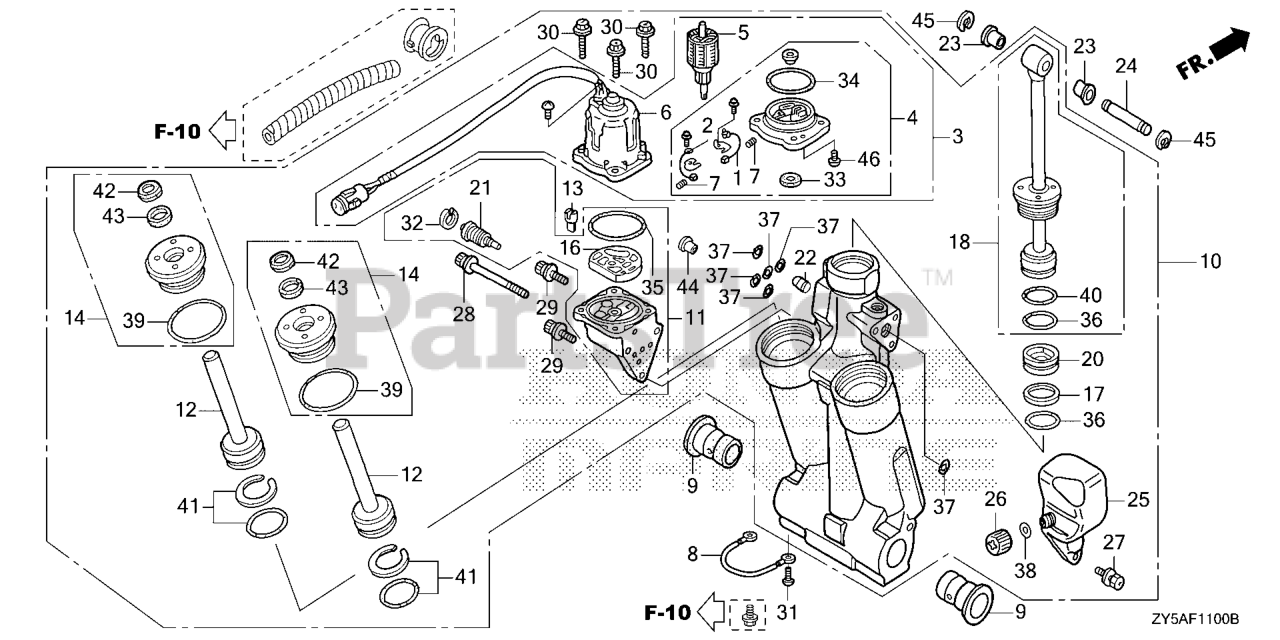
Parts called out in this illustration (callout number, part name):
1	BREAKER ASSY.
2	BRUSH ASSY.
3	MOTOR ASSY., POWER TILT
4	BRACKET ASSY.
6	YOKE ASSY.
7	SPRING, MOTOR
8	WIRE, LEAD (1.5X116MM)
9	BUSH, SWIVEL CASE
10	TRIM-TILT, POWER
10	TRIM-TILT ASSY., POWER
11	PUMP ASSY.
12	ROD, PISTON (B)
13	JOINT, DRIVE
14	GUIDE, ROD
16	FILTER (B)
17	RING, BACK-UP
18	ROD, PISTON
20	PISTON, FREE
21	VALVE, MANUAL
22	VALVE, RESERVOIR
23	BUSH, CYLINDER (LOWER)
24	PIN, CYLINDER (UPPER)
25	TANK, OIL
26	CAP, OIL TANK
27	BOLT, RECESSED
28	BOLT A, SOCKET
29	BOLT B, SOCKET
30	BOLT, HEX.
31	SCREW, PAN (6X8)
32	CIRCLIP (INNER)
34	O-RING (2.0X70.5)
35	O-RING (1.8X69.6)
36	O-RING (3.5X38.7)
37	O-RING (1.68X7.25)
38	O-RING (1.9X11)
39	O-RING (3.5X35.7)
40	O-RING (3.5X41.7)
41	O-RING SET (3.5X31.7)
42	SEAL, WATER
44	COLLAR, ORIFICE
45	E-RING (15MM)
46	SCREW (4X16)
